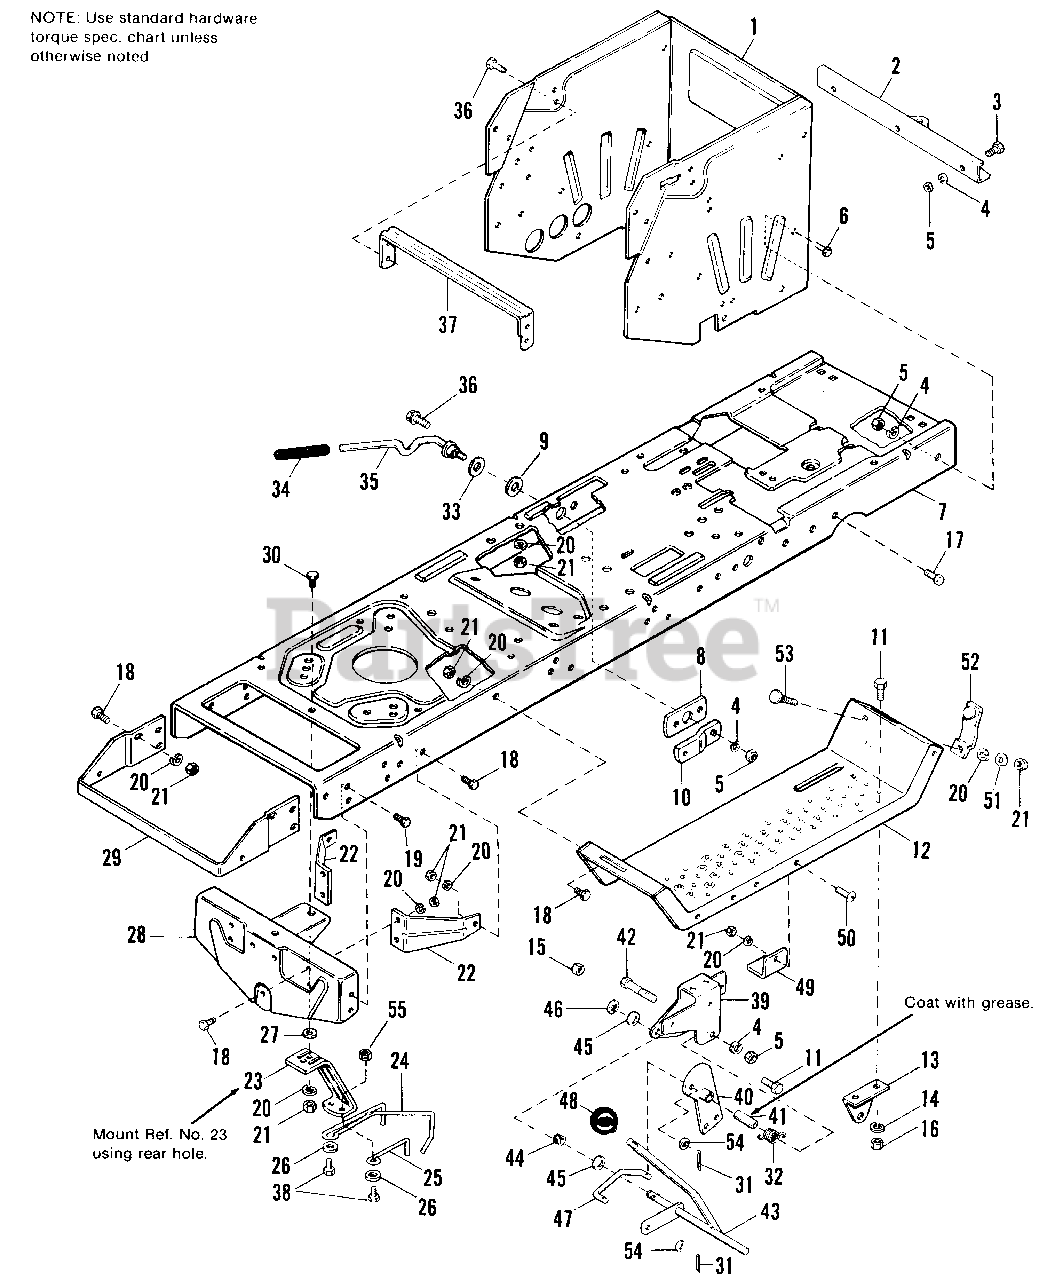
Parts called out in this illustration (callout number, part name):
1	SUPPORT, Axle, Wrapper
2	BAR, Draw
3	CAPSCREW, Hex Hd., 3/8-16 x 1
4	LOCKWASHER, 3/8
5	NUT, Hex, Full, 3/8-16
6	CAPSCREW, Hex Hd., 3/8-16 x 1-1/2
8	BAR, Support
10	ARM, Support
11	CAPSCREW, Hex Hd., 1/4-20 x 5/8
13	SUPPORT, Clutch
14	LOCKWASHER, 1/4
15	NUT, Flange, Whizlock, 1/4-20
16	NUT, Hex, 1/4-20
17	CAPSCREW, 3/8-16 x 3/4
18	CAPSCREW, Hex Hd., 5/16-18 x 3/4
19	SCREW, Hex Taptite, 5/16-18 x 3/4
20	LOCKWASHER, 5/16
21	NUT, Hex, Full, 5/16-18
22	BRACE, Axle Support
26	WASHER, Plain, 1/4
27	WASHER, Plain, 5/16
28	SUPPORT, Axle
29	SUPPORT, Hood
30	CAPSCREW, Hex Hd., 5/16-18 x 1
31	PIN, Cotter, 3/32 x 3/4
34	GRIP
35	HANDLE, Lift
36	SCREW, Hex Washer Hd., Taptite, 5/16-18 x 1/2
37	BRACE, Seat
38	CAPSCREW, 5/16-18 x 1-3/4
39	BRACKET, P.T.O.
40	ARM ASSY., P.T.O. Rod
42	CAPSCREW, Hex Hd., 3/8-16 x 2/1-4
43	HANDLE ASSY., P.T.O.
45	WASHER on P.T.O. Link
46	RING, Snap
47	LINK, P.T.O.
49	UP-STOP, Mower
50	SCREW, Truss Hd., Slotted, 5/16-18 x 3/4
52	LATCH ASSY.
53	BOLT, Carriage, 5/16-18 x 3/4
55	LOCKNUT, 5/16-18
